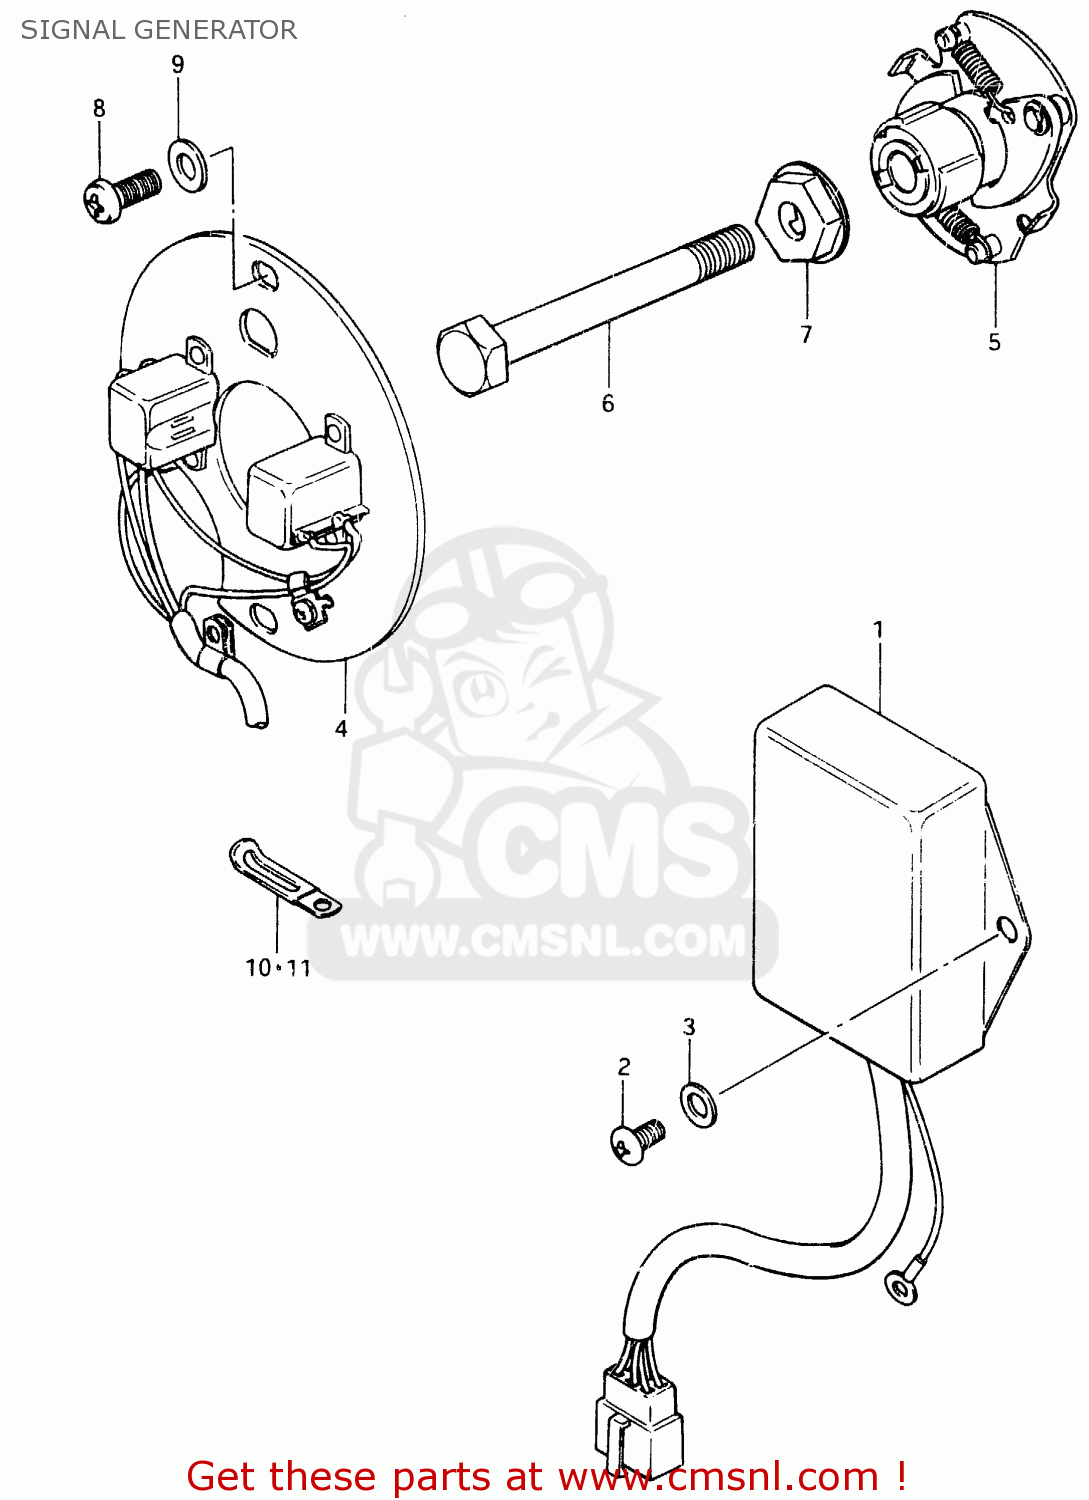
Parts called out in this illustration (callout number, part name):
1	IGNITOR UNIT
2	SCREW
3	WASHER
4	SIGNAL GENERATOR ASSY
5	GOVERNOR ASSY, ADVANCE
6	BOLT
7	WASHER
8	SCREW(5X12)
9	WASHER
10	CLAMP L:35
11	CLAMP
